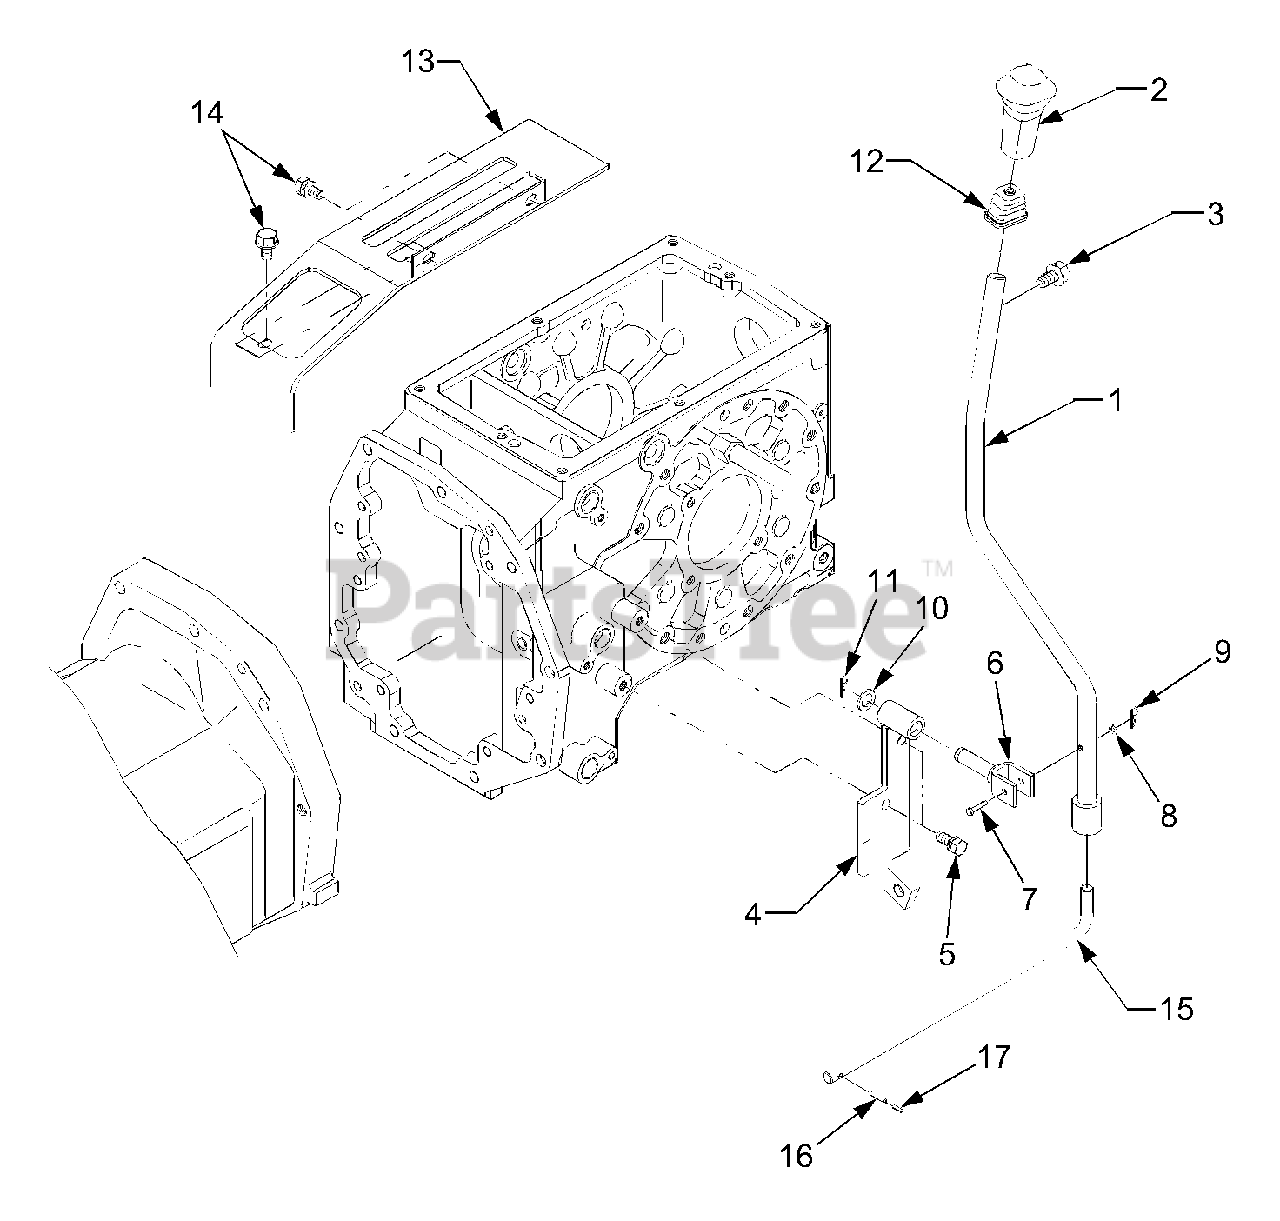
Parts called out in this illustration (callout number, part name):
1	Lever, Main Shift
2	Grip, Main Shift
4	Bracket, Main Shift
6	Pin, Main Shift
8	Washer, Plain
10	Washer, Plain
12	Boot, Main Shift
13	Guide, Shift Lever
15	Rod 1, Main Shift
